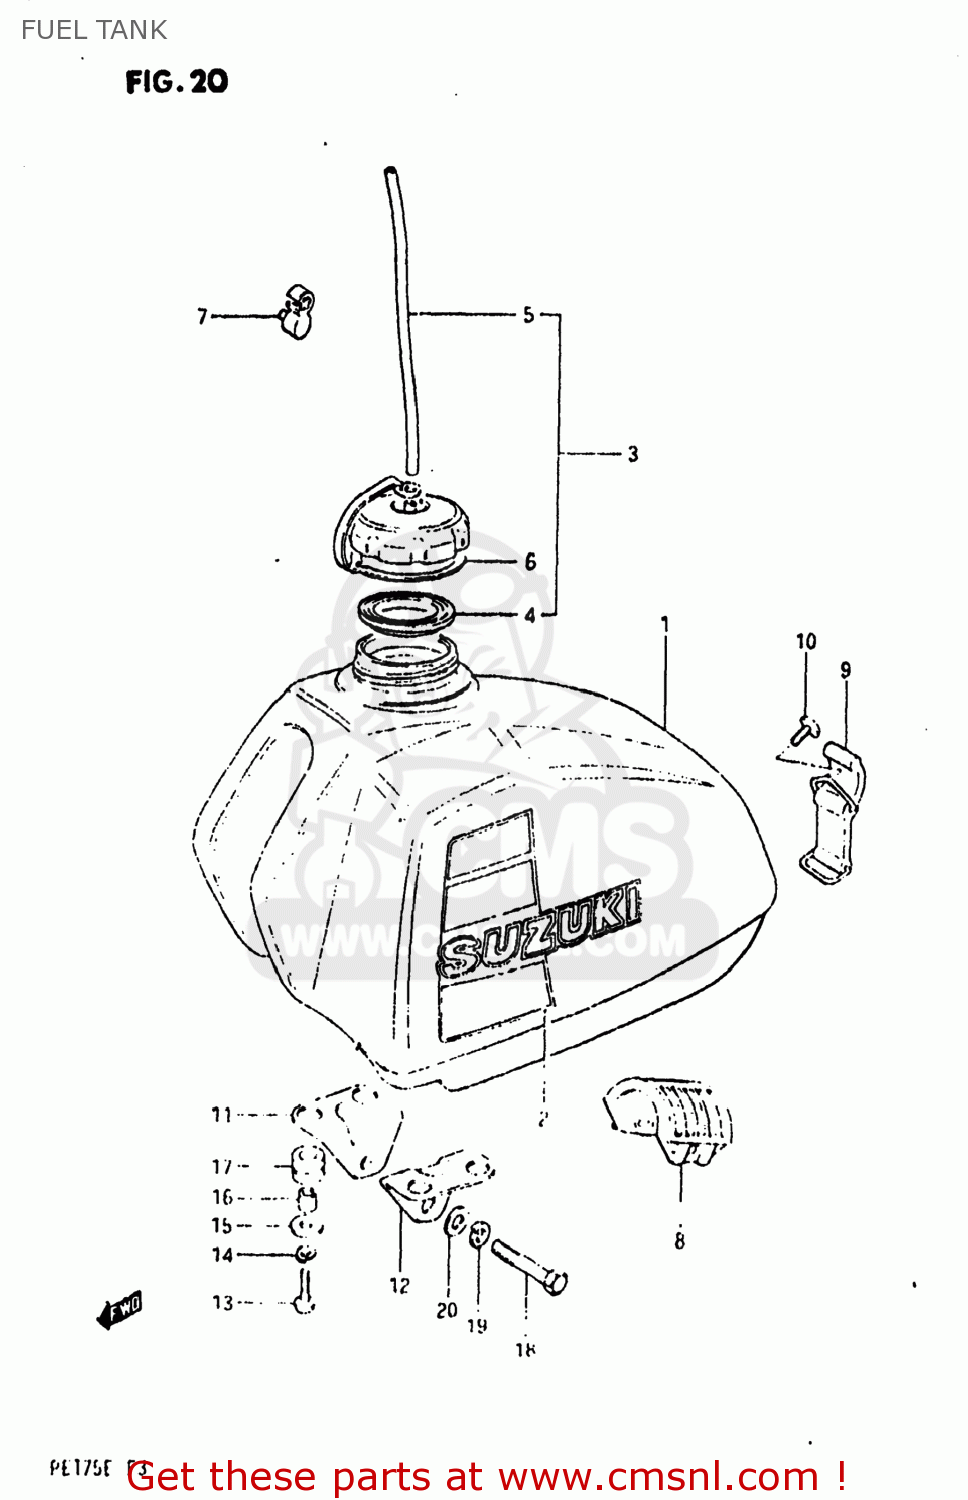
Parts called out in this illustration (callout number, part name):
1	TANK ASSEMBLY,FUEL
2	TAPE SET,FUEL TANK
3	CAP,FUEL TANK
4	GASKET,FUEL TANK CAP (NAS)
5	HOSE
6	BAND,FUEL TANK CAP
7	CLAMP,BREATHER HOSE
8	CUSHION,FUEL TANK
9	BAND,FUEL TANK,REAR
10	SCREW(6X18)
11	BRACKET,FUEL TANK,LOWER
12	BRACKET,FUEL TANK
13	SCREW
14	LOCK WASHER
15	WASHER (6.5X24X1.6)
16	SPACER(6.8X12X11)
17	CUSHION
18	HEXAGON BOLT 8X80
19	LOCK WASHER
20	WASHER
